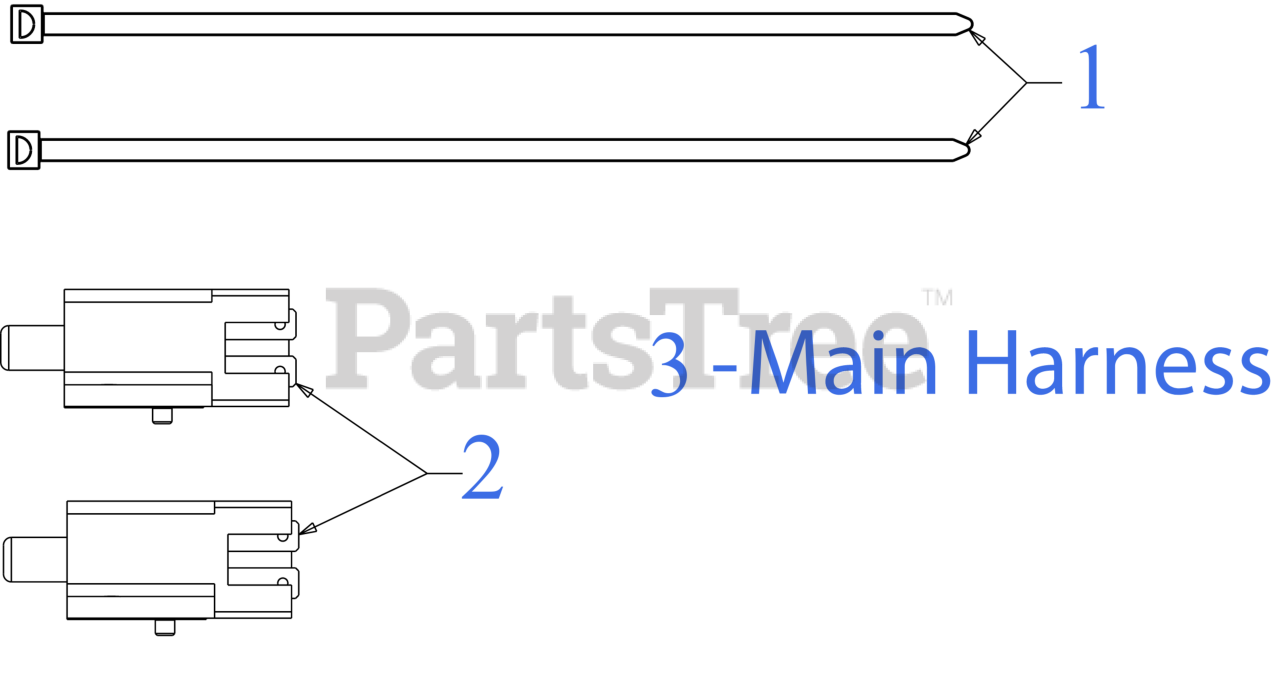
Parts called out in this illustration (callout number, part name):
1	7" CABLE TIE
2	INTERLOCK SWITCH (NO/NC)
3	MAIN HARNESS (RMC/AM/ACDC/BULB AGM)
3	12V SOLENOID
